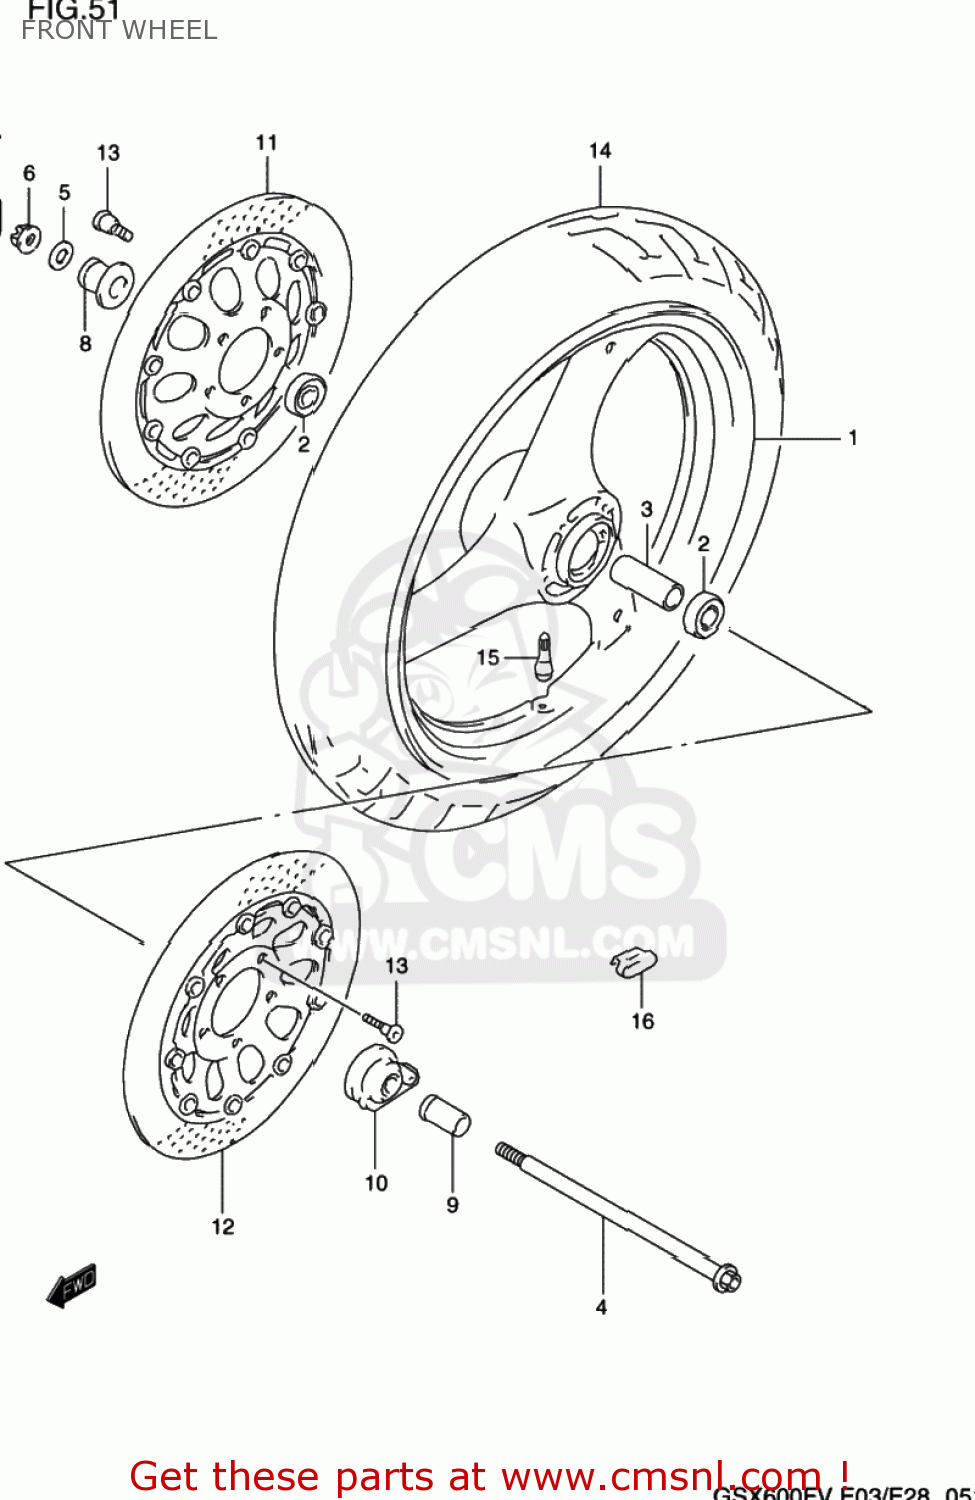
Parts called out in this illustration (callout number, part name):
1	WHEEL,FRONT (MT3.00X17)
2	BEARING
3	SPACER(15.3X21.7X63)
4	AXLE,FR
5	WASHER
6	NUT
7	COTTER PIN
8	SPACER,FR AXLE
9	SPACER,FR AXLE,L
10	BOX ASSEMBLY,SPEEDOMETER GEAR
11	DISC,FR BRAKE,R
12	DISC,FR BRAKE,L
13	BOLT 8X33
14	TIRE,FRONT 110/80-17.5
15	VALVE ASSEMBLY,WHEEL,TR412
16	BALANCER,WHEEL (10G)
